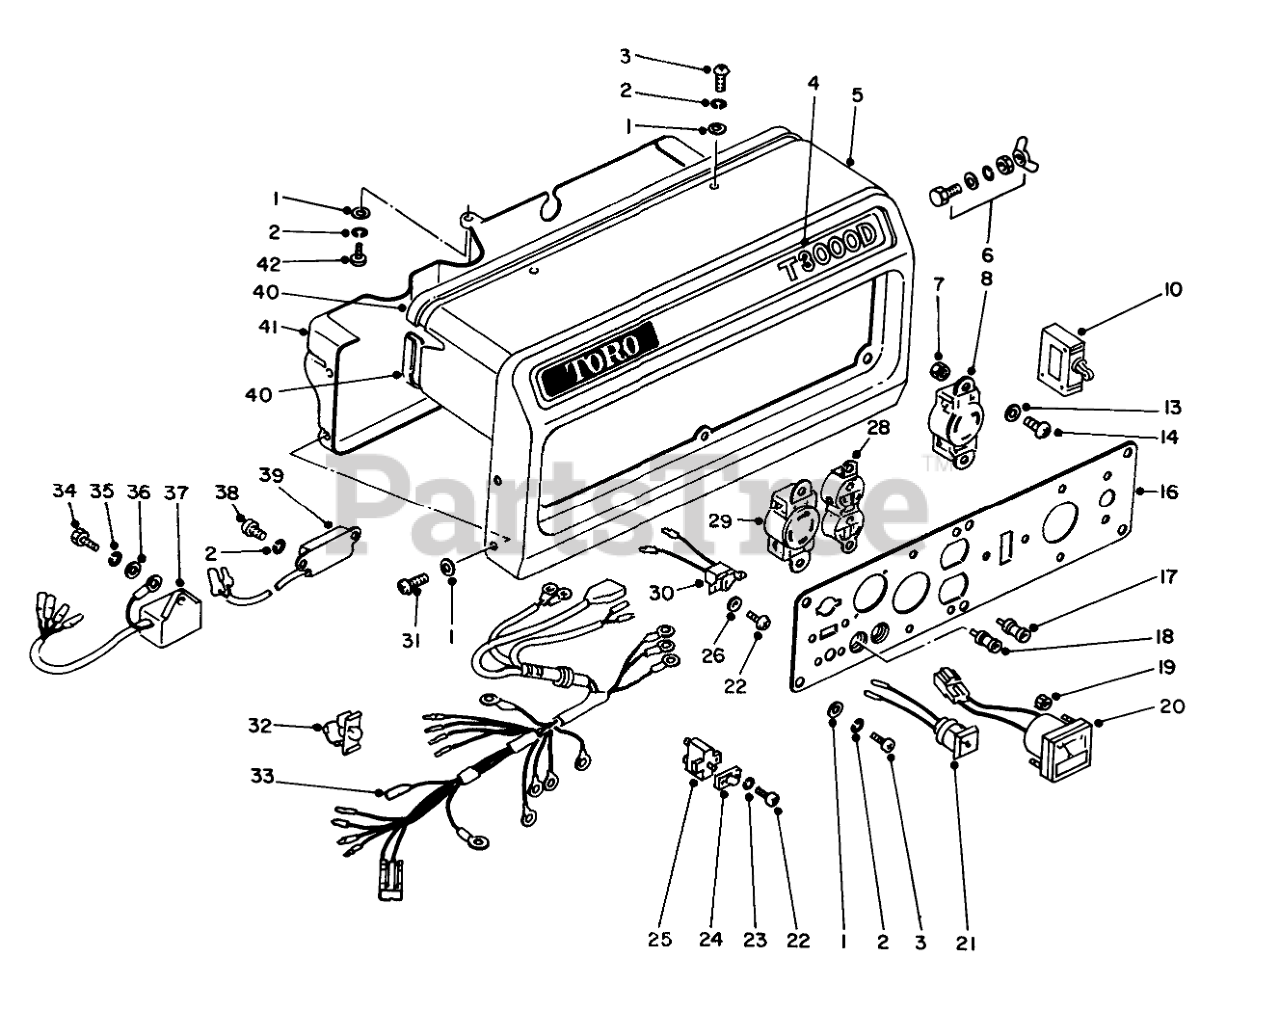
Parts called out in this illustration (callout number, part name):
1	WASHER
2	Washer
3	SCREW
4	Emblem-Toro
5	Panel-Control
6	GROUND TERMINAL
8	Receptacle (125V, 30A )
10	CIRCUIT BREAKER
13	Washer
14	Screw
16	Plate-Panel
18	TERMINAL-
20	Meter-Voltage
22	Screw
23	Washer
25	Circuit Breaker DC
26	Washer
28	Receptacle (125V, 15A)
29	Receptacle
30	Switch
31	Screw
32	Clamp
33	CONTROL HARNESS
35	LOCKWASHER
36	Washer
37	OIL LEVEL UNIT
38	Screw
39	X-STR MAG UNIT
41	Panel-Rear
42	Screw
